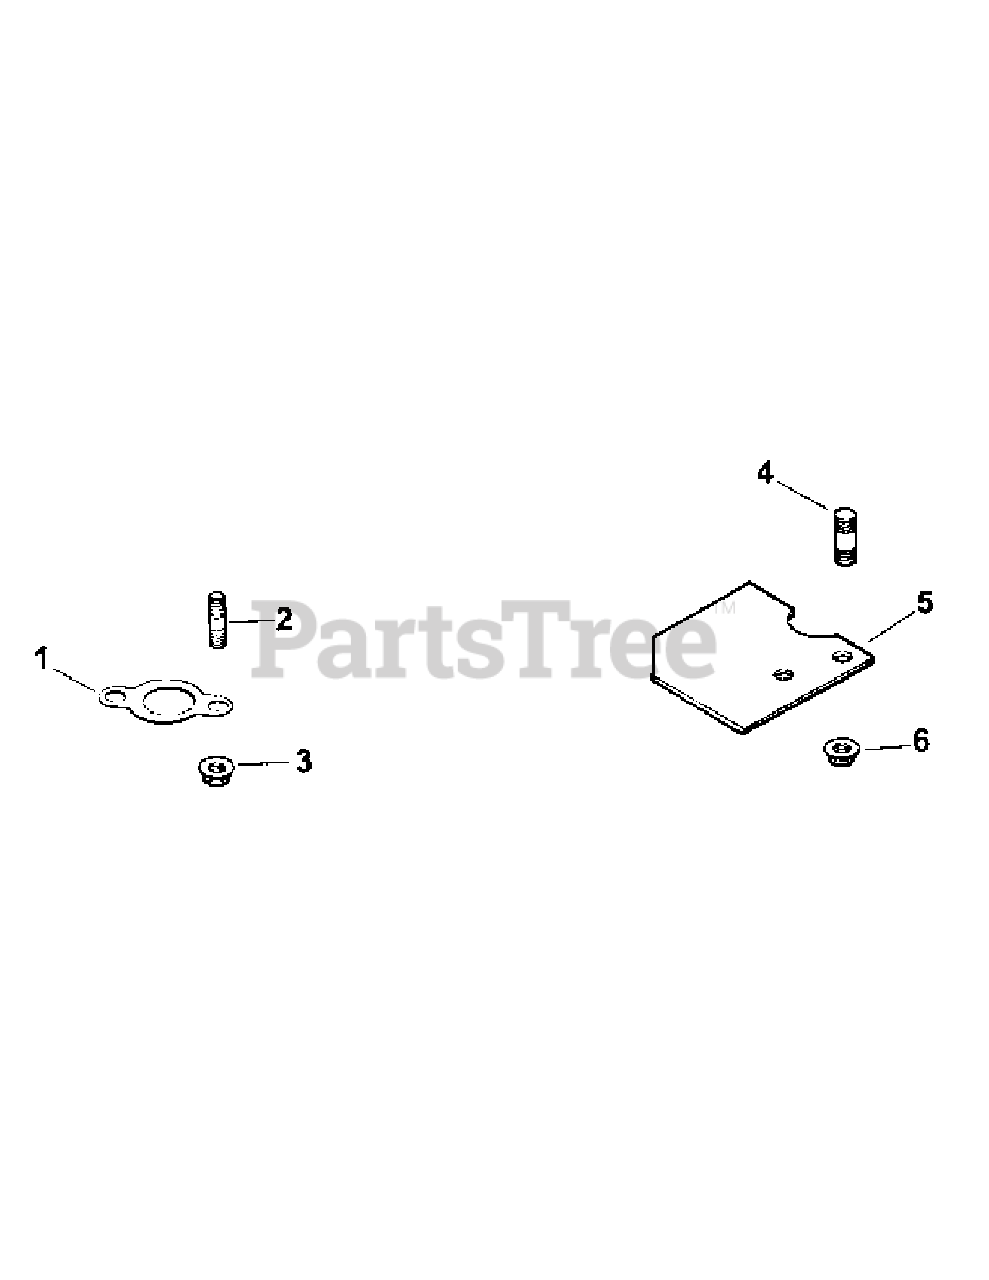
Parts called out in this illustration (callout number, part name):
1	Stud (M8 x 1.25 x 33)
2	Exhaust Gasket
3	Muffler Mounting Nut (M8 x 1.25)
4	Exhaust Stud
5	Heat Deflector
6	Hex Flange Nut (M6 x 1.0)
